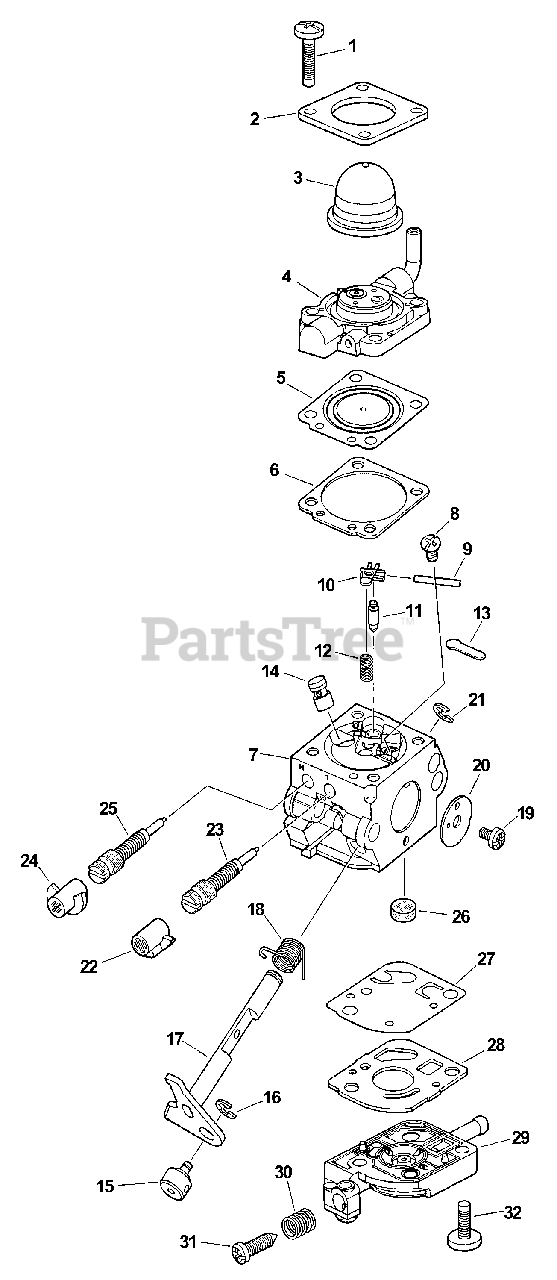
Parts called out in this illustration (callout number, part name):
1	SCREW, RETAINER
2	RETAINER, PURGE BULB
3	BULB, PURGE
4	BASE, PURGE
5	DIAPHRAGM, METERING
6	GASKET, METERING
7	BODY, CARBURETOR
8	SCREW, METERING LEVER PIN
9	PIN, METERING LEVER
10	LEVER, METERING
11	VALVE, INLET NEEDLE
12	SPRING, METERING LEVER
13	PLUG, WELCH
14	NOZZLE, CHECK VALVE
16	RING, RETAINING
17	SHAFT, THROTTLE
18	SPRING, RETURN
20	VALVE, THROTTLE
21	RING, RETAINING
22	CAP, LIMITER
23	NEEDLE - LOW SPEED
24	CAP, LIMITER
25	NEEDLE - HIGH SPEED
26	STRAINER
27	DIAPHRAGM, PURGE
28	GASKET, PURGE
29	BASE, PURGE
30	SPRING, IDLE ADJUST
31	SCREW, IDLE ADJUST
32	SCREW, PUMP COVER
